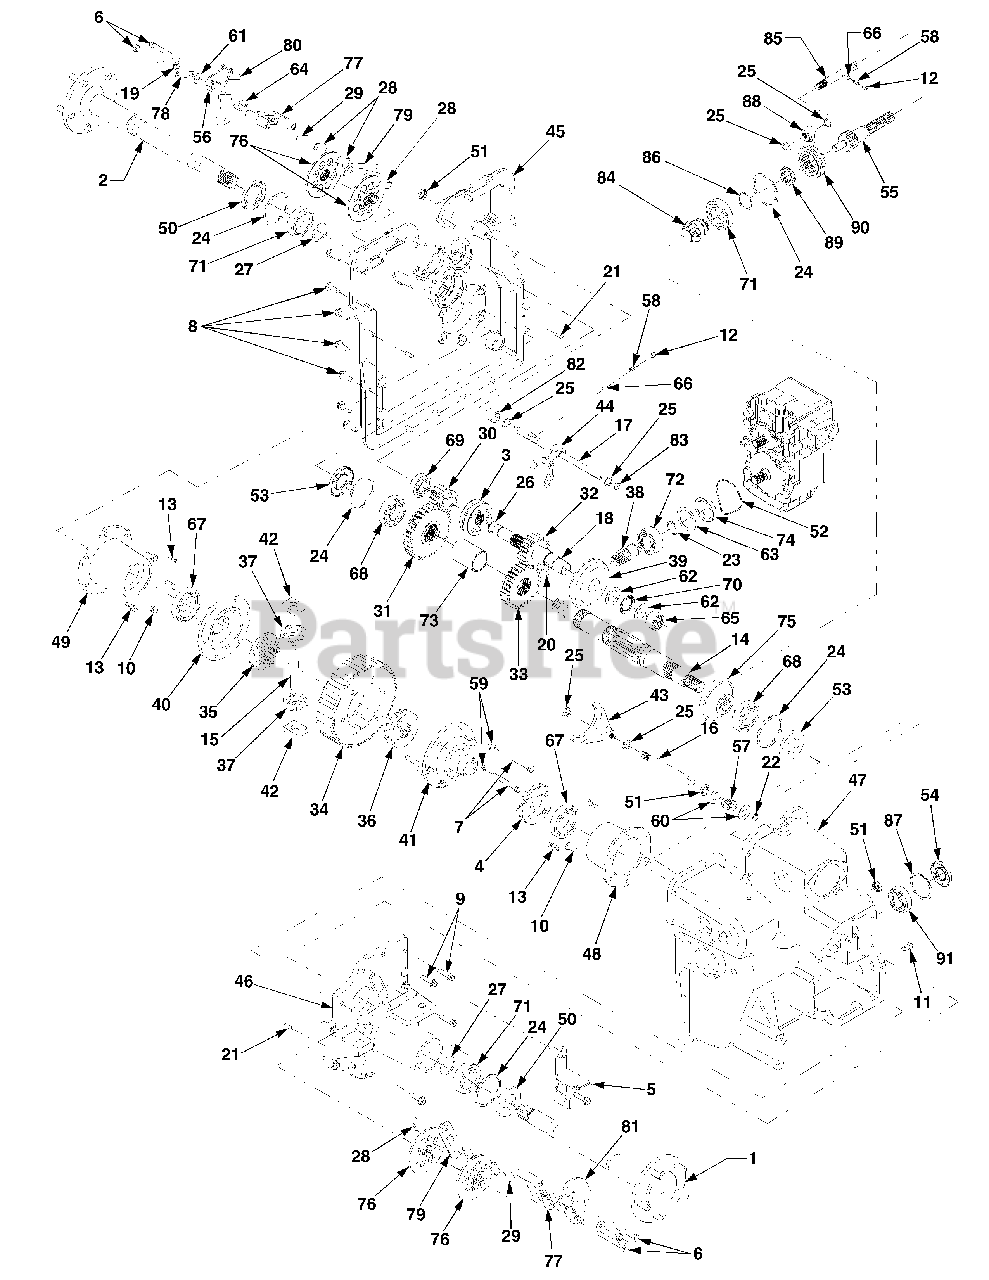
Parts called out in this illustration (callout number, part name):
1	Shaft, Axle RH
2	Shaft, Axle LH
3	Collar Assembly, Hi-Lo
4	Collar Assembly, Diff Lock
5	Bracket, Diff. Lock
6	Screw, Hex Cap, 5/16-18 x 2.75 GR5
7	Screw, Hex Cap, 5/16-18 x 2.5 GR5
8	Screw, Hex Wash. Hd. Tapp, 5/16-18 x 1.0
9	Screw, Hex Wash. Hd. Tapp, 5/16-18 x 1.25
10	Screw, Hex Cap, w/Patch 5/16-18 x .75GR5
11	Screw, Plug, M14 x 1.5 x .827
12	Screw, Set, 5/16-18 x .375
13	Screw, Shoulder .309 x .375: 1/4-20
14	Shaft, Output, 11T
15	Shaft, Cross, .625 x 3.95
16	Shaft, Diff. Lock Actuator
17	Shaft, Hi-Lo Actuator
18	Shaft, Drive
19	Nut, Hex Insert Lock, 5/16-24
20	Key, Woodruff, 1/4 x 3/4
21	Pin, Dowel, .25 x .75
22	Ring, Retaining
23	Ring, Snap
24	Ring, Retaining
25	Clip, Rotor
26	Ring, Retaining
27	Ring, Retaining
28	Pad, Brake
29	Plate, Brake Puck
30	Gear, Spur, 12T
31	Gear, Spur, 34T
32	Gear, Spur, 19T
33	Gear, Spur, 27T
34	Gear, Spur, 56T
35	Gear, Bevel, 16T
36	Gear, Bevel, 16T Lock
37	Gear, Bevel, 10T Diff.
38	Gear, Spiral Bevel, 13T
39	Gear, Spiral Bevel, 54T
40	Cover, Differential
41	Cover, Differential Lock
42	Block, Thrust
43	Yoke, Diff. Lock Actuator
44	Yoke, Shift, Hi-Lo
45	Cover, Trans. Large
46	Cover, Trans. Small
47	Housing, Trans.
48	Housing, Axle Inner - RH
49	Housing, Axle Inner - LH
50	Seal, Oil
51	Seal, Oil
52	Seal, Gland
53	Seal, Oil
54	Seal, Oil
55	Shaft, 4WD
56	Spring, Torsion
57	Spring, Compression, .845 x 1.0
58	Spring, Compression, .24 x .563
59	Washer, Lock, 5/16
60	Washer, Flat, .597 x 1.0 x .04
61	Washer, Flat, .343 x .88 x .062
62	Washer, Thrust
63	Washer, Flat, 1.52 x 2.0 x .030
64	Pin, Brake Actuating
65	Bearing, Needle
66	Ball, Detent
67	Bearing, Ball
68	Bearing, Ball
69	Bearing, Ball
70	Bearing, Needle Thrust
71	Bearing, Ball
72	Bearing, Ball
73	Spacer, 1.51 x 1.75 x 2.41
74	Spacer, 1.515 x 2.039 x .335
75	Gear, Spiral Bevel, 36T
76	Disc, Brake
77	Yoke, Brake
78	Bracket, Brake Anti Rotation
79	Plate, Puck Retainer
80	Arm, Brake Actuator - LH
81	Arm, Brake Actuator - RH
82	Spacer, .573 x .938 x .832
83	Plug, .437 x .16
84	Gear Assembly w/Bearings
85	Shaft, 4WD Actuator
86	Ring, Retaining
87	Ring, Retaining
88	Yoke, 4WD
89	Gear, Spline Coupling
90	Collar, Shift
91	Bearing, Ball
